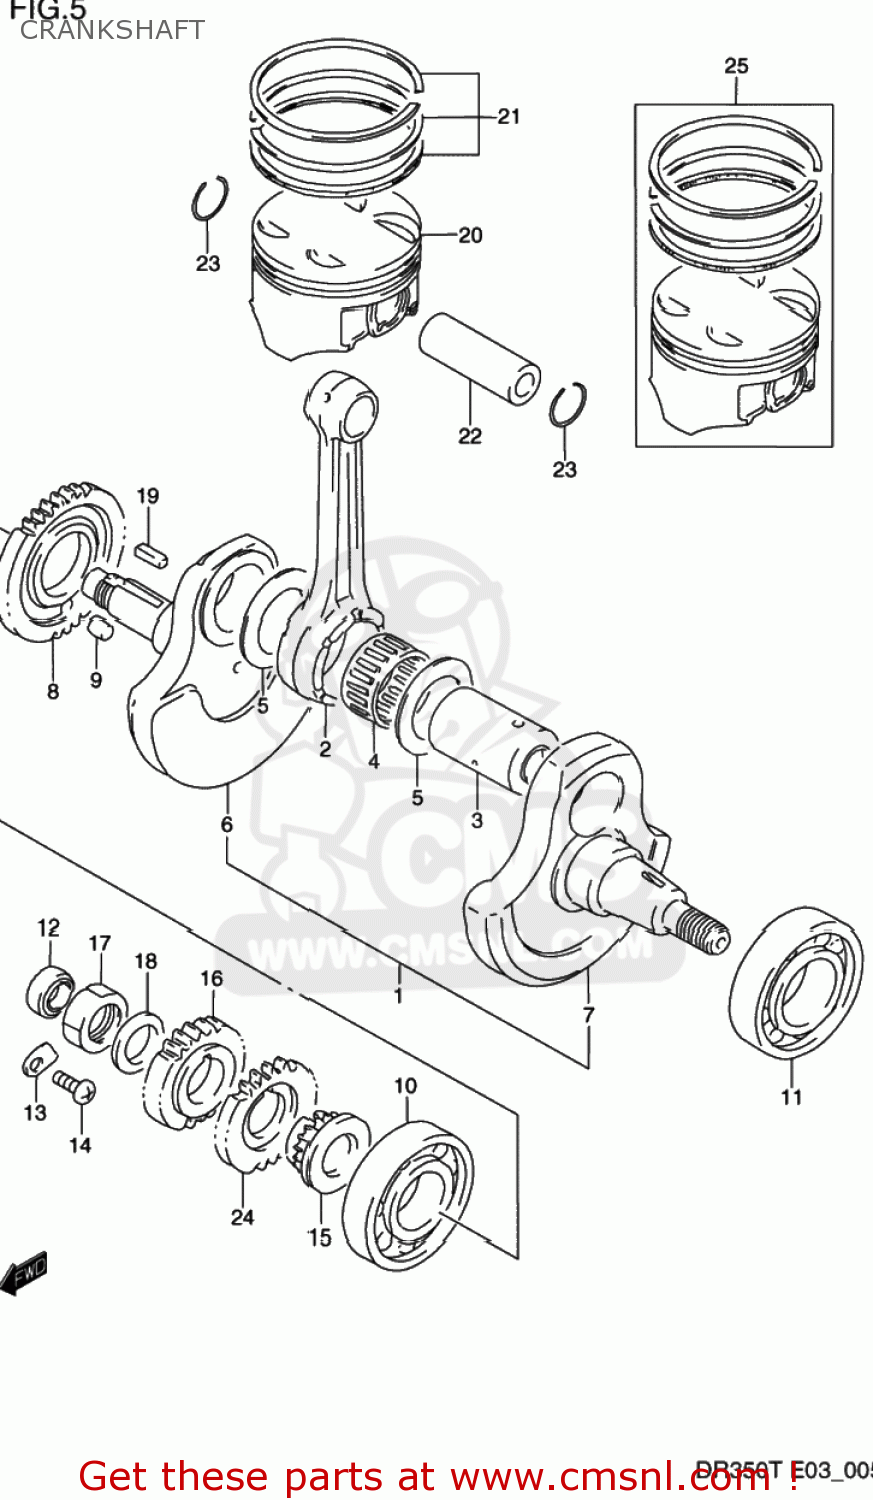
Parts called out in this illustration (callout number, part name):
1	CRANKSHAFT ASSY
2	ROD,CONNECTING
3	PIN COMP,CRANK
4	BEARING(34X43X22)
5	WASHER(34X52X1)
6	CRANKSHAFT
7	CRANKSHAFT,L
8	GEAR,CRANK BAL DRIVE(NT:37)
9	PIN
10	BEARING(30X72X19)
11	BEARING(35X72X17)
12	SEAL,OIL(14X24X6)
13	RETAINER,BEARING
14	SCREW
15	SPROCKET,CAM CHAIN DRIVE
16	GEAR,PRIMARY DRIVE
17	NUT
18	WASHER
19	KEY
20	PISTON
21	RING SET,PISTON
22	PIN,PISTON
23	CIRCLIP,PISTON PIN
24	GEAR,OIL PUMP DRIVE (NT
25	PISTON SET (OS:1.0)
